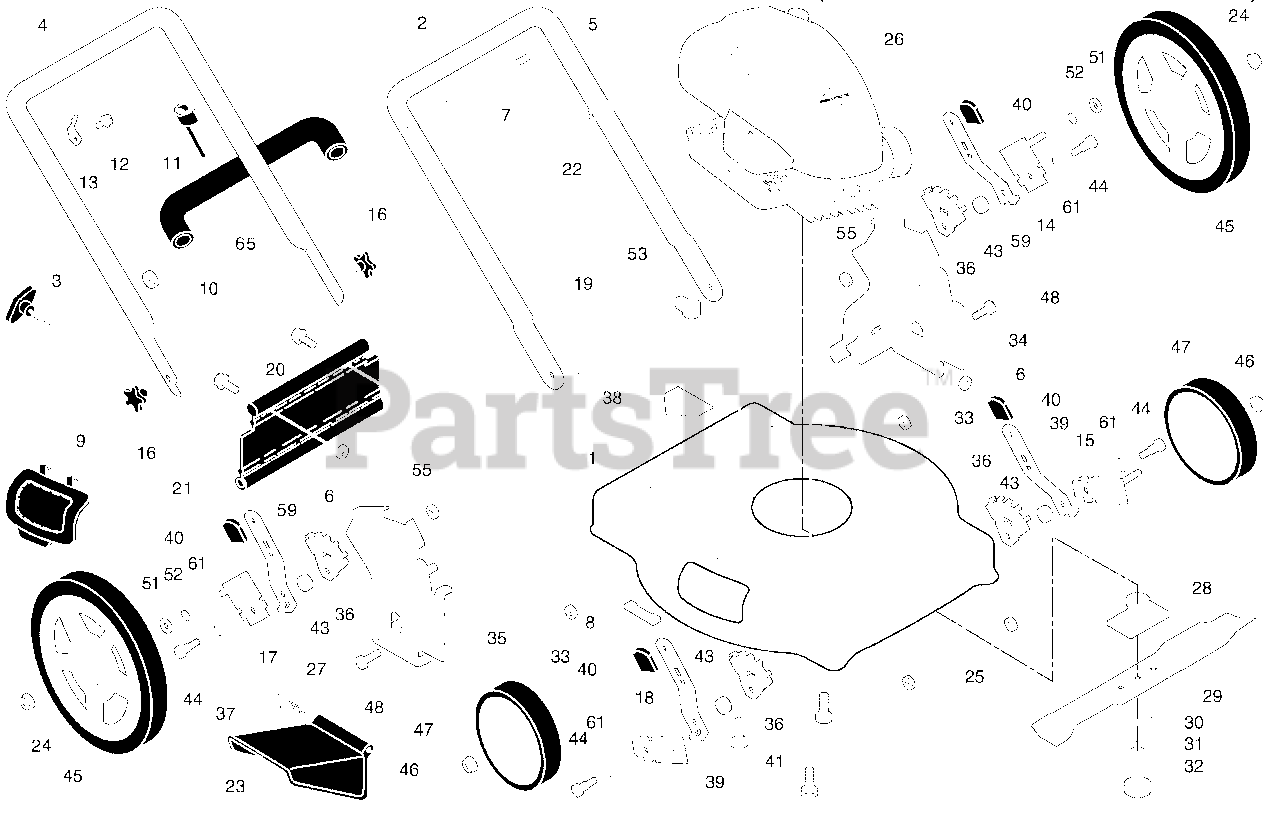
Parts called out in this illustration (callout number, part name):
1	Kit, Lawn Mower Housing
2	Control Bar
3	Rope Guide
4	Upper Handle Assembly
5	Lower Handle
6	Locknut, Hex 1/4-20
7	Handle Bolt 5/16-18
8	Clip, Closeout
9	Mulcher Plate
10	Nut, Hex 1/4-20
11	Engine Zone Control Cable
12	Hex Washer Head Screw #10-24 x 1/2
13	Up-Stop Bracket
14	Axle Arm Assembly, Rear, LH
15	Axle Arm Assembly, Front, LH
16	Knob, Handle
17	Axle Arm Assembly, Rear, RH
18	Axle Arm Assembly, Front, RH
19	Hairpin Cotter
20	Screw, Hex Cap Head 1/4-20
21	Rear Deflector
22	Wire Tie
23	Discharge Guard
24	Nut, Hex, Flangelock 3/8-16
25	Nut, Hex, Flangelock 5/16-18
27	Torsion Spring
28	Blade Adapter
29	22" Blade
30	Hardened Washer
31	Helical Lockwasher 3/8
32	Screw, Hex Head, Grade 8, 3/8-24 x 1-3/8
33	Nut, Hex, Nylock 5/16-18
34	Handle Bracket, LH
35	Handle Bracket, RH
36	Wheel Bracket Adjuster
37	Hinge Rod
38	Danger Decal
39	Selector Spring, Front
40	Selector Knob
41	Screw, Hex Head, Threaded, Rolled 3/8-16 x 1
43	Spacer
44	Shoulder Bolt 5/16-18
45	Wheel & Tire Assembly, Rear, 12"
46	Nut, Hex, Flangelock 3/8-16
47	Wheel & Tire Assembly, Front, 7"
48	Bolt, Hex Head 5/16-18
51	Washer, Flat 3/8
52	O-Ring
53	Clip, Cable
58	Nut, Hex
59	Selector Spring, Rear
61	Washer, Curved, Cylindrical
65	Grip, Foam
65	Operator's Manual, English
65	Operator's Manual, French
65	Repair Parts Manual
